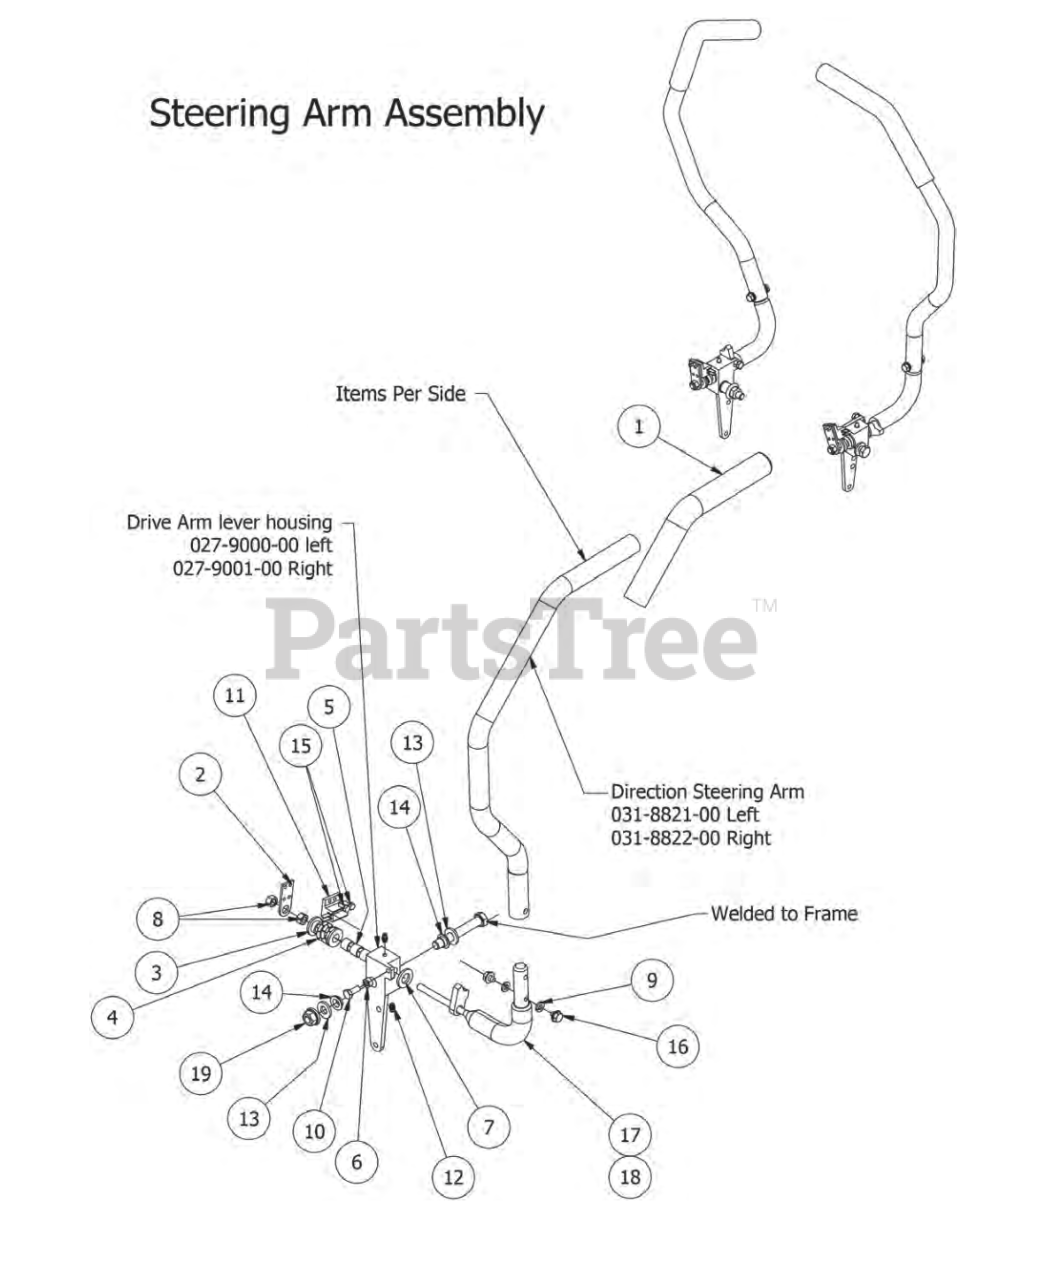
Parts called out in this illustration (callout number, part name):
1	Rubber Grip
2	MZ Switch Bracket
3	.515 ID Nylon Shoulder Washer
4	Drive Lever Spring
5	.507 ID Nylon Bushing
7	.505 ID Plastic Washer
8	1/2"-13 Nylon Insert Jam Locknut
9	5/16" Lock Washer
10	5/16" x 3/4" Hex Bolt
11	Safety Switch
12	1/4" Press in Grease Fitting
13	.505x1x.125 Oil Impregnated washer
14	Bushing For 2012 Drive arm
15	12-24x 1/2 HWH Bolt
16	5/16-18 1/2 HWH Bolt-Steering
17	Black Steering Arm Elbow (Right)
18	Black Steering Arm Elbow (Left)
19	1/2-13 Hex Flange (GR.G) ZC
